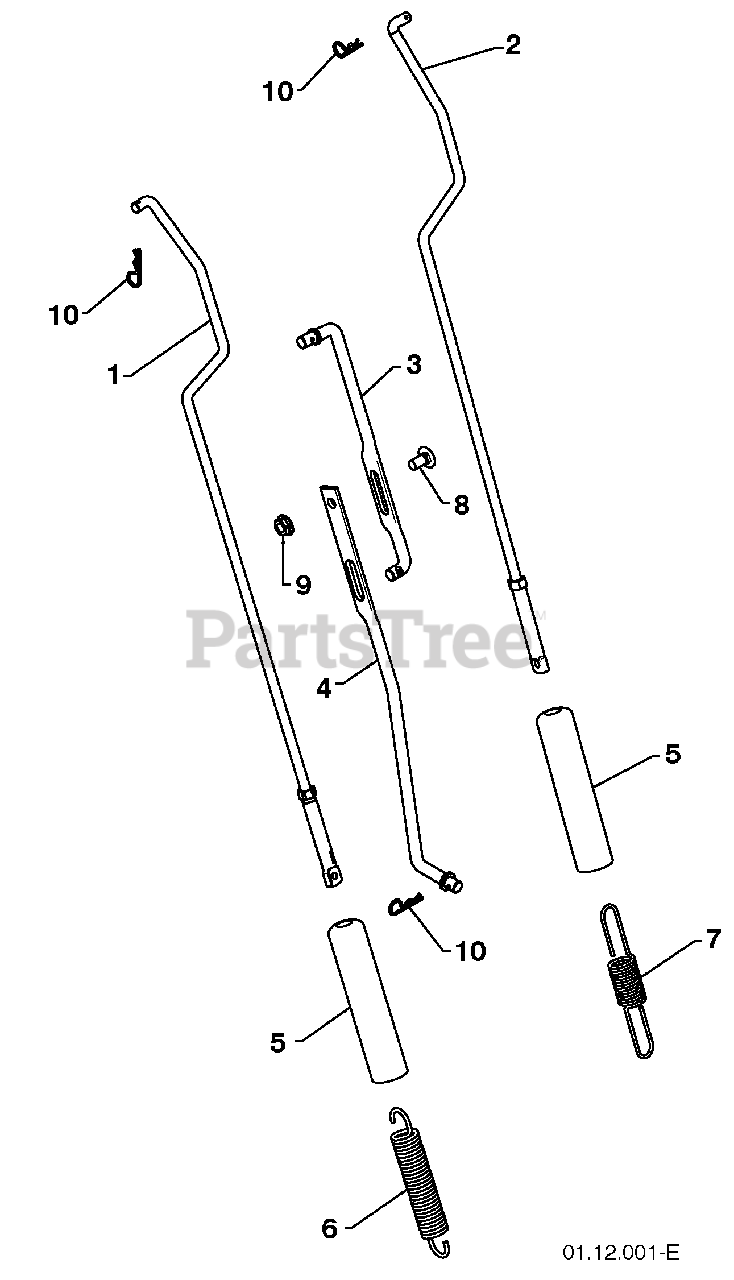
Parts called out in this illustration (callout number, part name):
1	IMPELLER ROD ASSEMBLY
2	TRACTION ROD ASSEMBLY
3	SHIFTER ROD TOP
4	SHIFTER ROD BOTTOM
5	SPRING SLEEVE
6	IMPELLER SPRING
7	TRACTION SPRING
8	CARRIAGE BOLT 5/16-18 X .75
9	NUT 5/16-18
10	RETAINER
